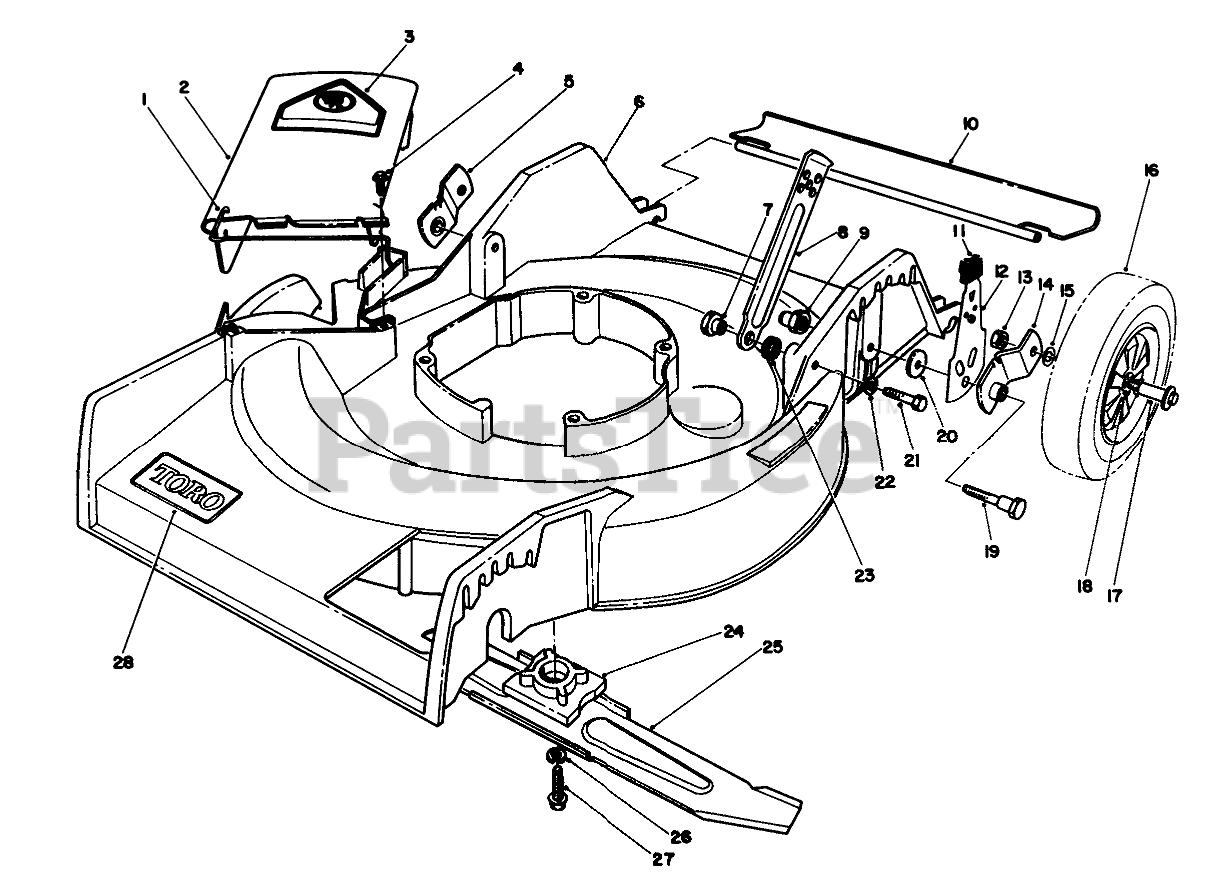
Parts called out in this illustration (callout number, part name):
1	SPRING HINGE
2	Deflector (Incl. Ref. #1 & 3)
3	DECAL-DANGER
4	SCREW-HWH
5	Pivot Arm
6	HOUSING W/DECAL
7	HANDLE PIVOT NUT
8	HANDLE LATCH
9	HANDLE PIVOT NUT
10	SHIELD - TRAILING
11	KNOB-ARM
12	REAR SPRING ARM ASM
13	Nut
14	Pivot Arm
15	WASHER
16	Wheel & Tire Assembly (Incl. Ref. #18)
17	BOLT-WHEEL
18	BUSHING
19	5/16-18 PIVOT SCREW
20	PIVOT WASHER
21	SCREW-HH
22	WASHER-LOCK
23	SPACER
24	BLADE RETAINER
25	Blade
26	WASHER-LOCK
27	SCREW-HH
28	DECAL
